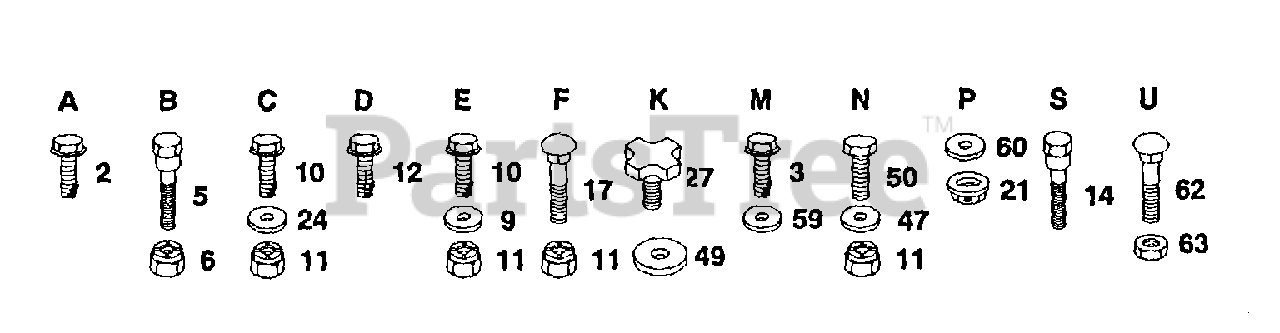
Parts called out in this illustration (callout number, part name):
2	SCREW
3	SCREW GTV
9	WASHER
12	SCREW LT
14	"BOLT,SHOULDER"
17	BOLT
21	PAL NUT LT
24	WASHER
27	"KNOB 1/2"" YT"
47	WASHER
49	WASHER
50	BOLT
59	WASHER
60	WASHER PM
62	BOLT
